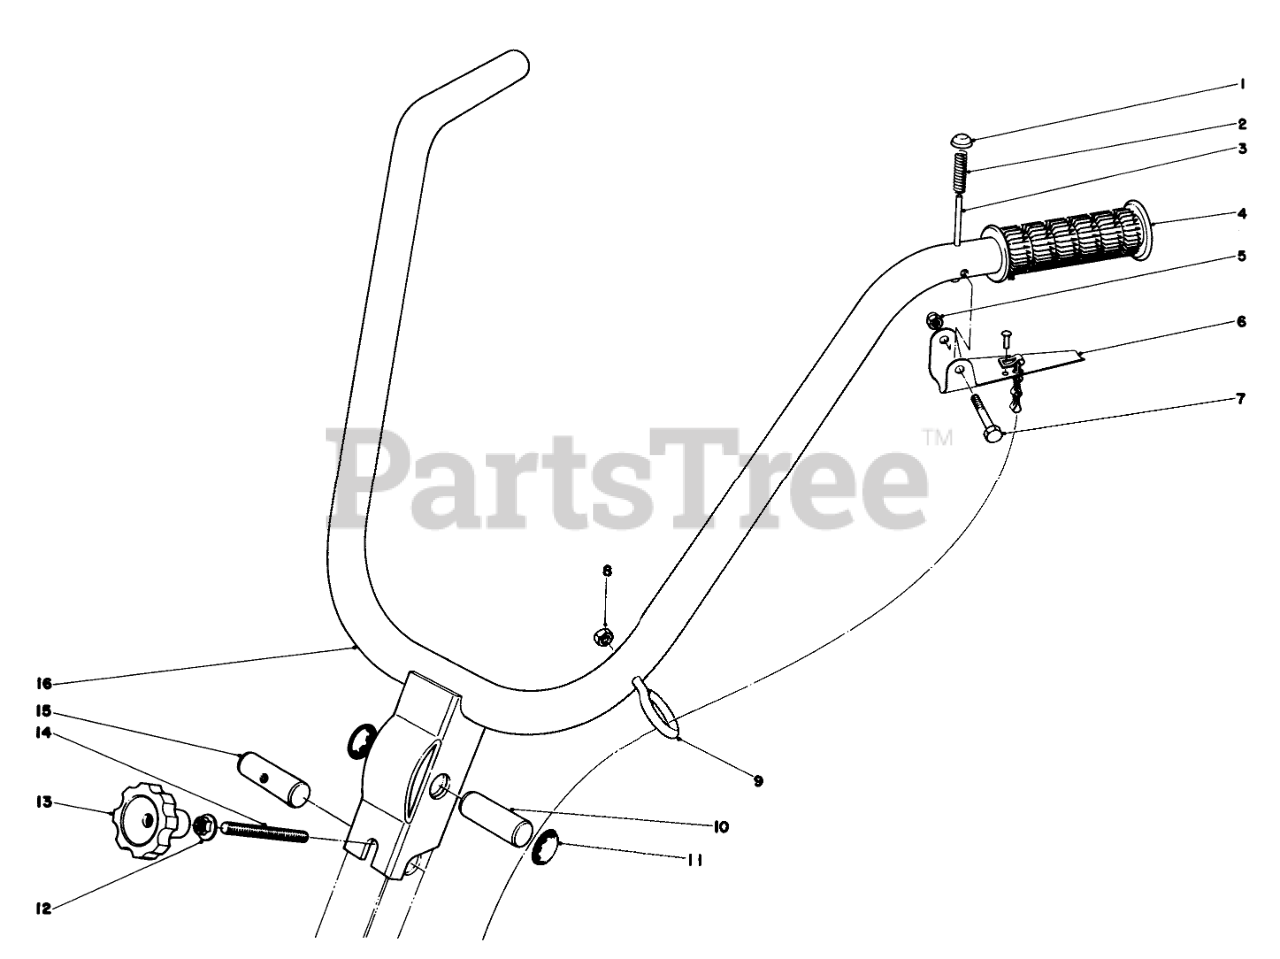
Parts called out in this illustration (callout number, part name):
1	Push-On
2	COMPRESSION SPRING
3	LOCK PIN
4	GRIP-HANDLE
5	NUT-CAP
6	Lift Bail Chain Assembly
7	SCREW-HH
8	NUT-HEX, SIDE DEFORM
9	Eye Bolt
10	PIVOT PIN
11	PUSH-ON
12	NUT-FLANGE
15	Pin Handle
16	HANDLE BAR WA
